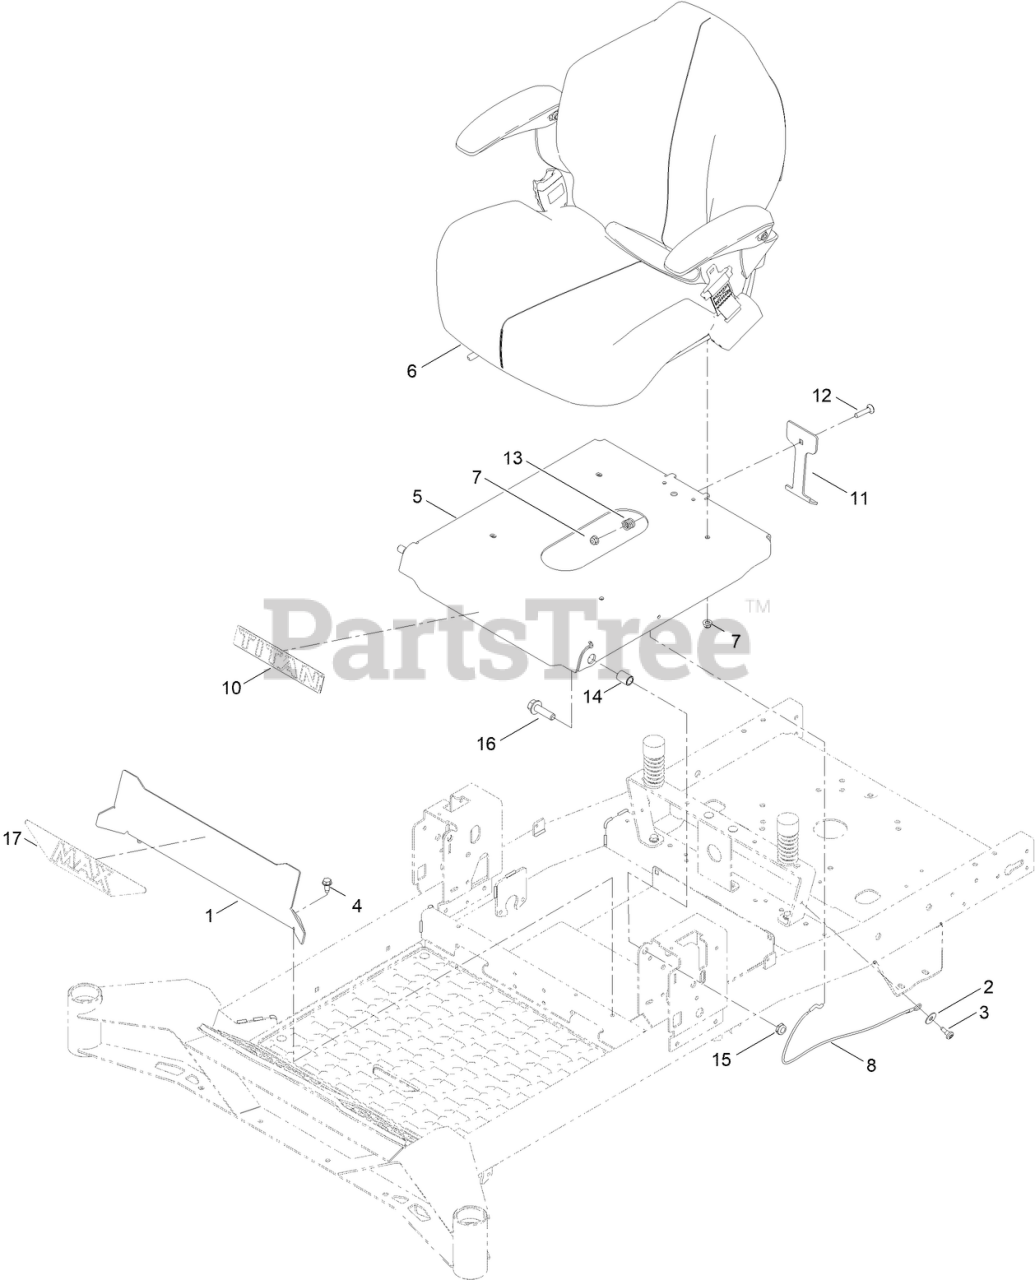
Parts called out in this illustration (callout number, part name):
1	PLATE-KICK
2	WASHER-FLAT
3	SCREW-SHOULDER
4	SCREW-HWHTF
5	PAN-SEAT
6	SEAT ASM
7	NUT-HF, NI
8	CABLE-LANYARD
10	DECAL-TITAN
11	BRACKET-LATCH, SEAT
12	BOLT-CARR
13	SPRING-COMPRESSION
14	BUSHING-PIVOT, SEAT
15	NUT-HEX
16	SCREW-HHF
17	DECAL- TC HAVOC
